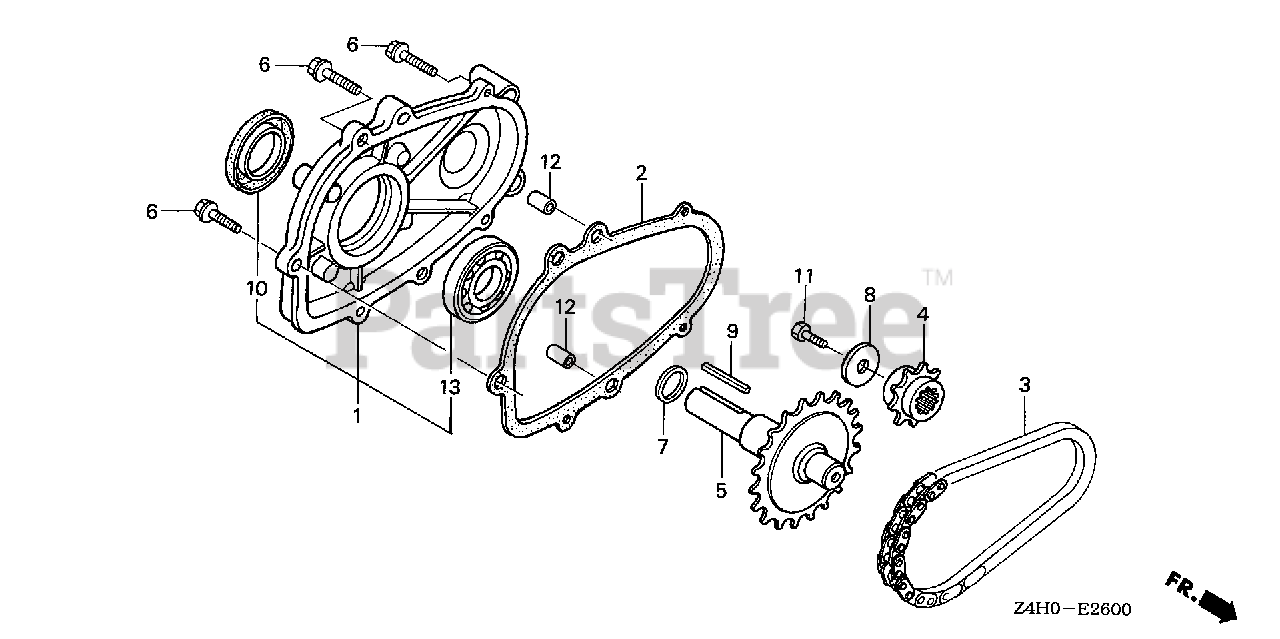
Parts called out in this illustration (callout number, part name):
1	COVER ASSY., CHAIN CASE
2	GASKET, CHAIN CASE COVER
3	CHAIN, P.T.O. DRIVE (DID270S-DHA-36LE)
4	SPROCKET, DRIVE (14T)
5	SHAFT, P.T.O. (28T)
6	BOLT, FLANGE (6X28) (CT200)
7	SPRING, THRUST
8	WASHER (8MM)
9	KEY (5X5X33) (YELLOW)
10	OIL SEAL (25X41X6) (NOK)
11	BOLT, HEX. (8X25)
12	PIN, DOWEL (8X14)
13	BEARING, RADIAL BALL (6205)
